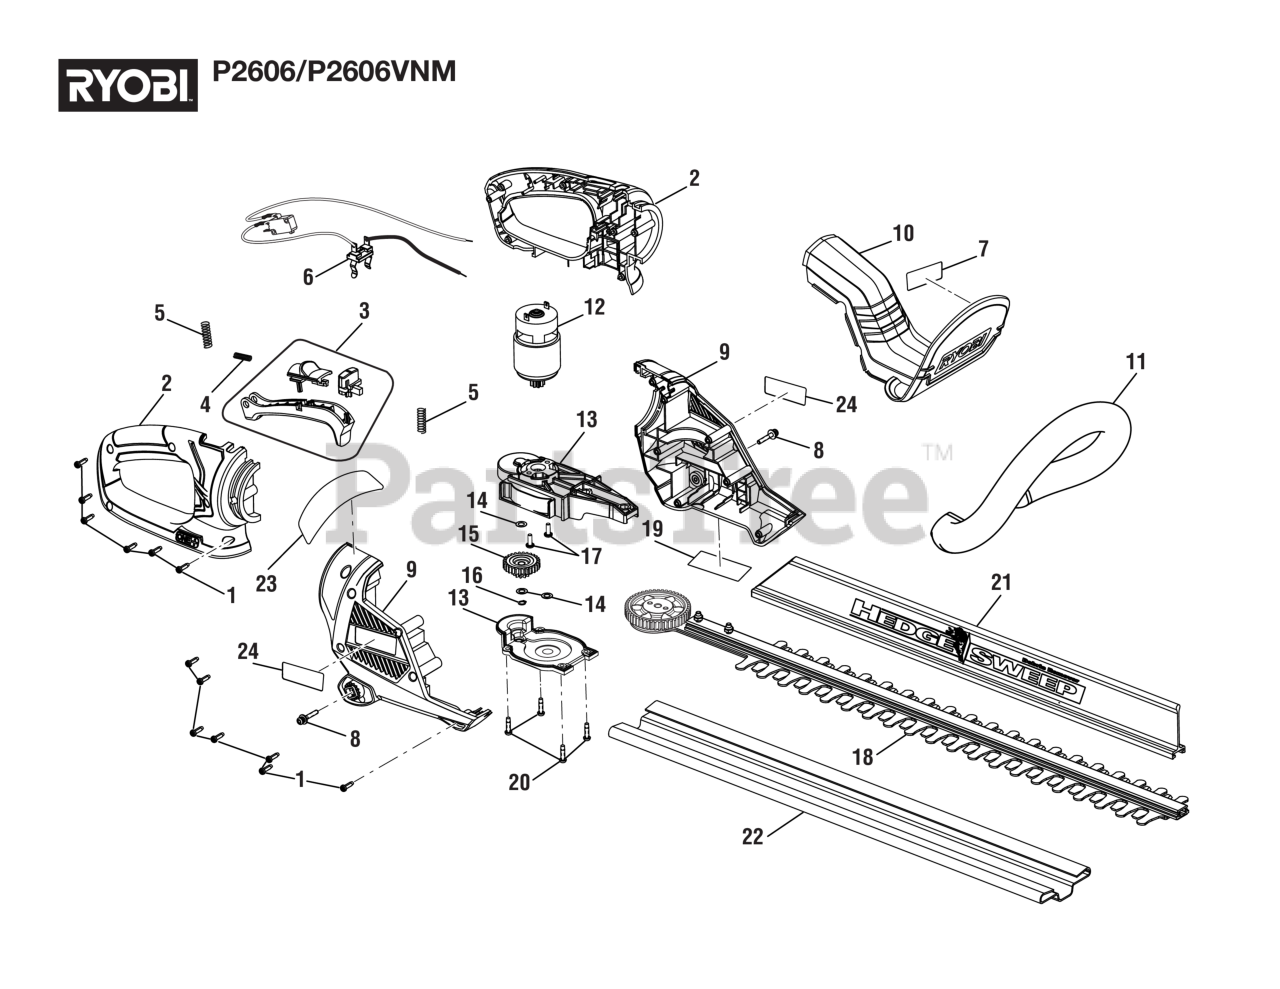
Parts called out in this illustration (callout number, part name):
1	Screw (M4 x 14 mm, T15 Torx Pan Hd.))
2	Handle Assembly
3	Trigger Assembly
4	Lock-Off Button Spring
5	Compression Spring
6	Wiring Harness
7	Warning Label
8	Screw w/Washers (M4 x 26 mm, T15 Torx Pan Hd.)
9	Housing Assembly
10	Top Cover Assembly
11	Front Handle
12	Motor and Pinion Assembly
13	Gear Box w/Cover Assembly
14	Washer (M6, ID6.2 x 11OD x 0.3t)
15	Center Gear
16	RETAINING RING (EXTERNAL)
17	Screw w/Tooth Washer (M4 x 12 mm, Pan Hd.)
18	Blade Assembly
19	Data Label
20	Screw (M4 x 16 mm, Pan Hd.)
21	Hedge Sweep
22	Blade Shield
23	Rotating Handle Label
24	Logo Label
